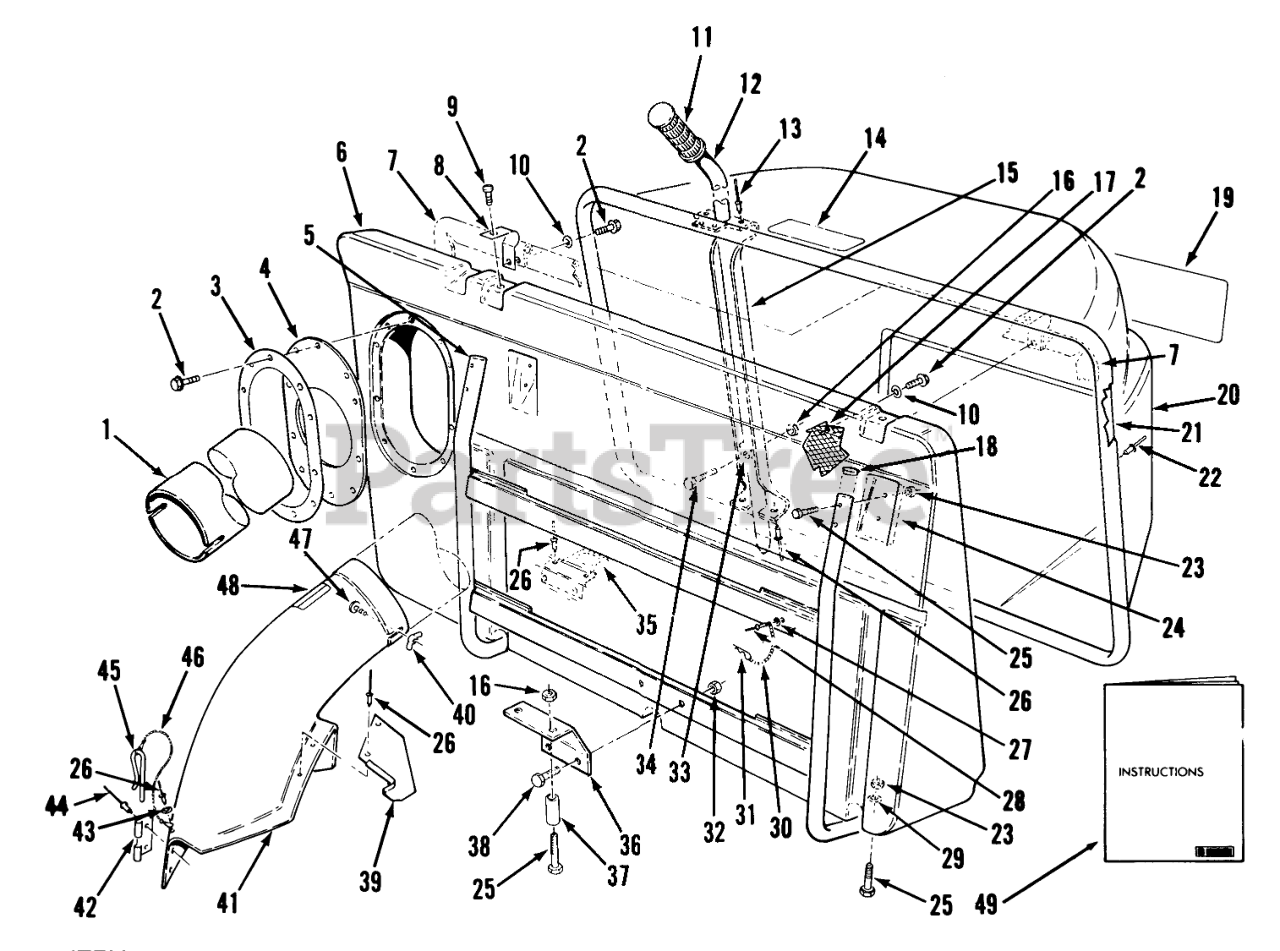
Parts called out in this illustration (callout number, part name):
1	TUBE(ROUND&LONG)
2	SCREW-HWHTF
3	RING-RETAINING
4	RING-RETAINER, RUBBER
5	Frame
6	BAG-FRONT
7	SEAL-BAG
8	Bracket-Hinge
9	SCREW-HSBH
10	WASHER-FLAT
11	GRIP-HANDLE
12	HANDLE-DUMP
13	RIVET-POP
14	Decal Warning
15	Channel-Dump Handle
17	Screen Bag
19	DECAL - TORO
20	BASKET-GRASS
21	Frame-Grass Basket
23	NUT-LOCK, NI
24	Plate-Backup
25	SCREW-HH
26	RIVET-BLIND
27	WASHER
29	WASHER-FLAT
30	10 LINK CHAIN W/O HOOK
31	PIN-HAIR
32	NUT-LOCK, NI
33	GUIDE-HANDLE, DUMP
34	SCREW-HH
35	Latch
36	Bracket-Hitch
37	Spacer
38	SCREW-HH
39	CHUTE SUPT BRKT
40	NUT-WING SPECL
41	Chute Assembly (includes Reference #26, 39-48)
42	BRACKET-MOUNTING, CHUTE
43	WASHER-PLAIN
44	RIVET-BLIND
45	PIN-LOCKING, CHUTE
46	LANYARD
47	BOLT-CARR
48	DECAL-DANGER
49	59176/78 EASY-EMPTY
